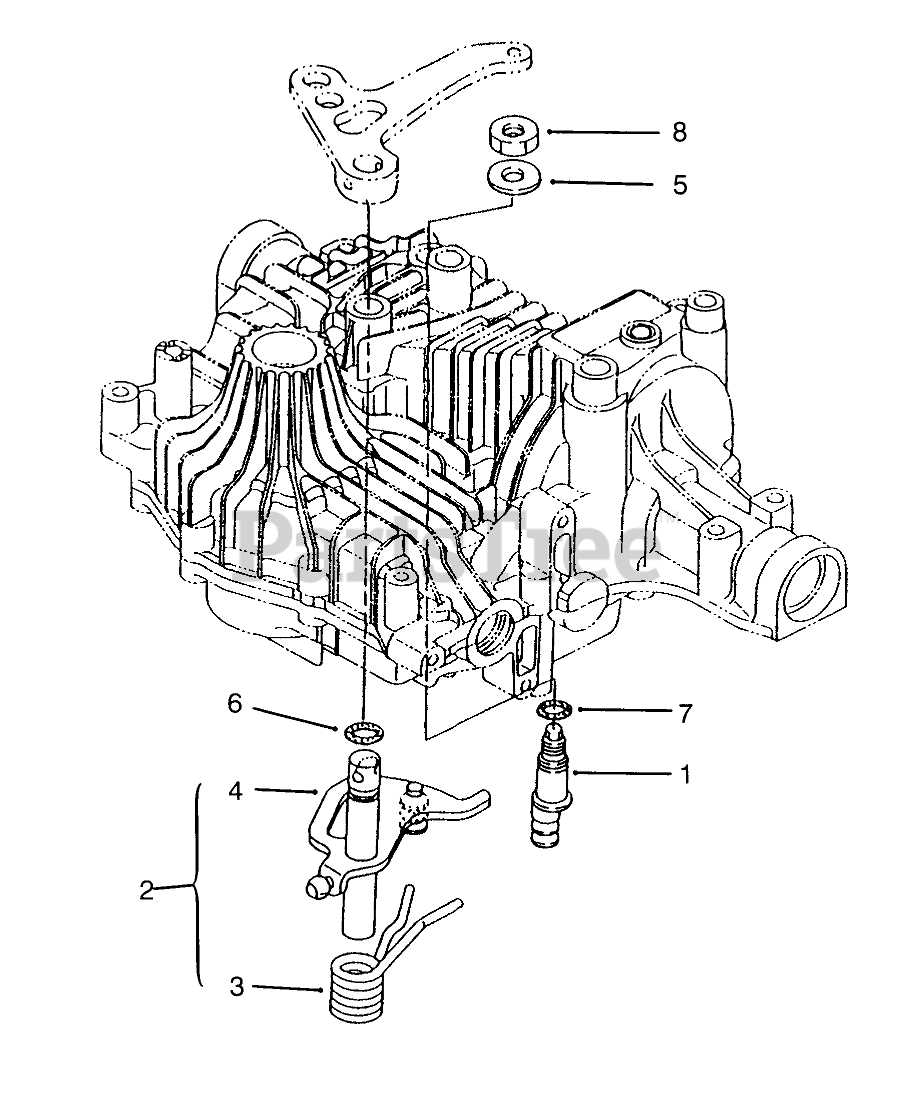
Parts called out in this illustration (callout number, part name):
1	FULCRUM
2	SHAFT ASM
4	Shaft-Control
5	WASHER
6	O-RING
7	PACKING
